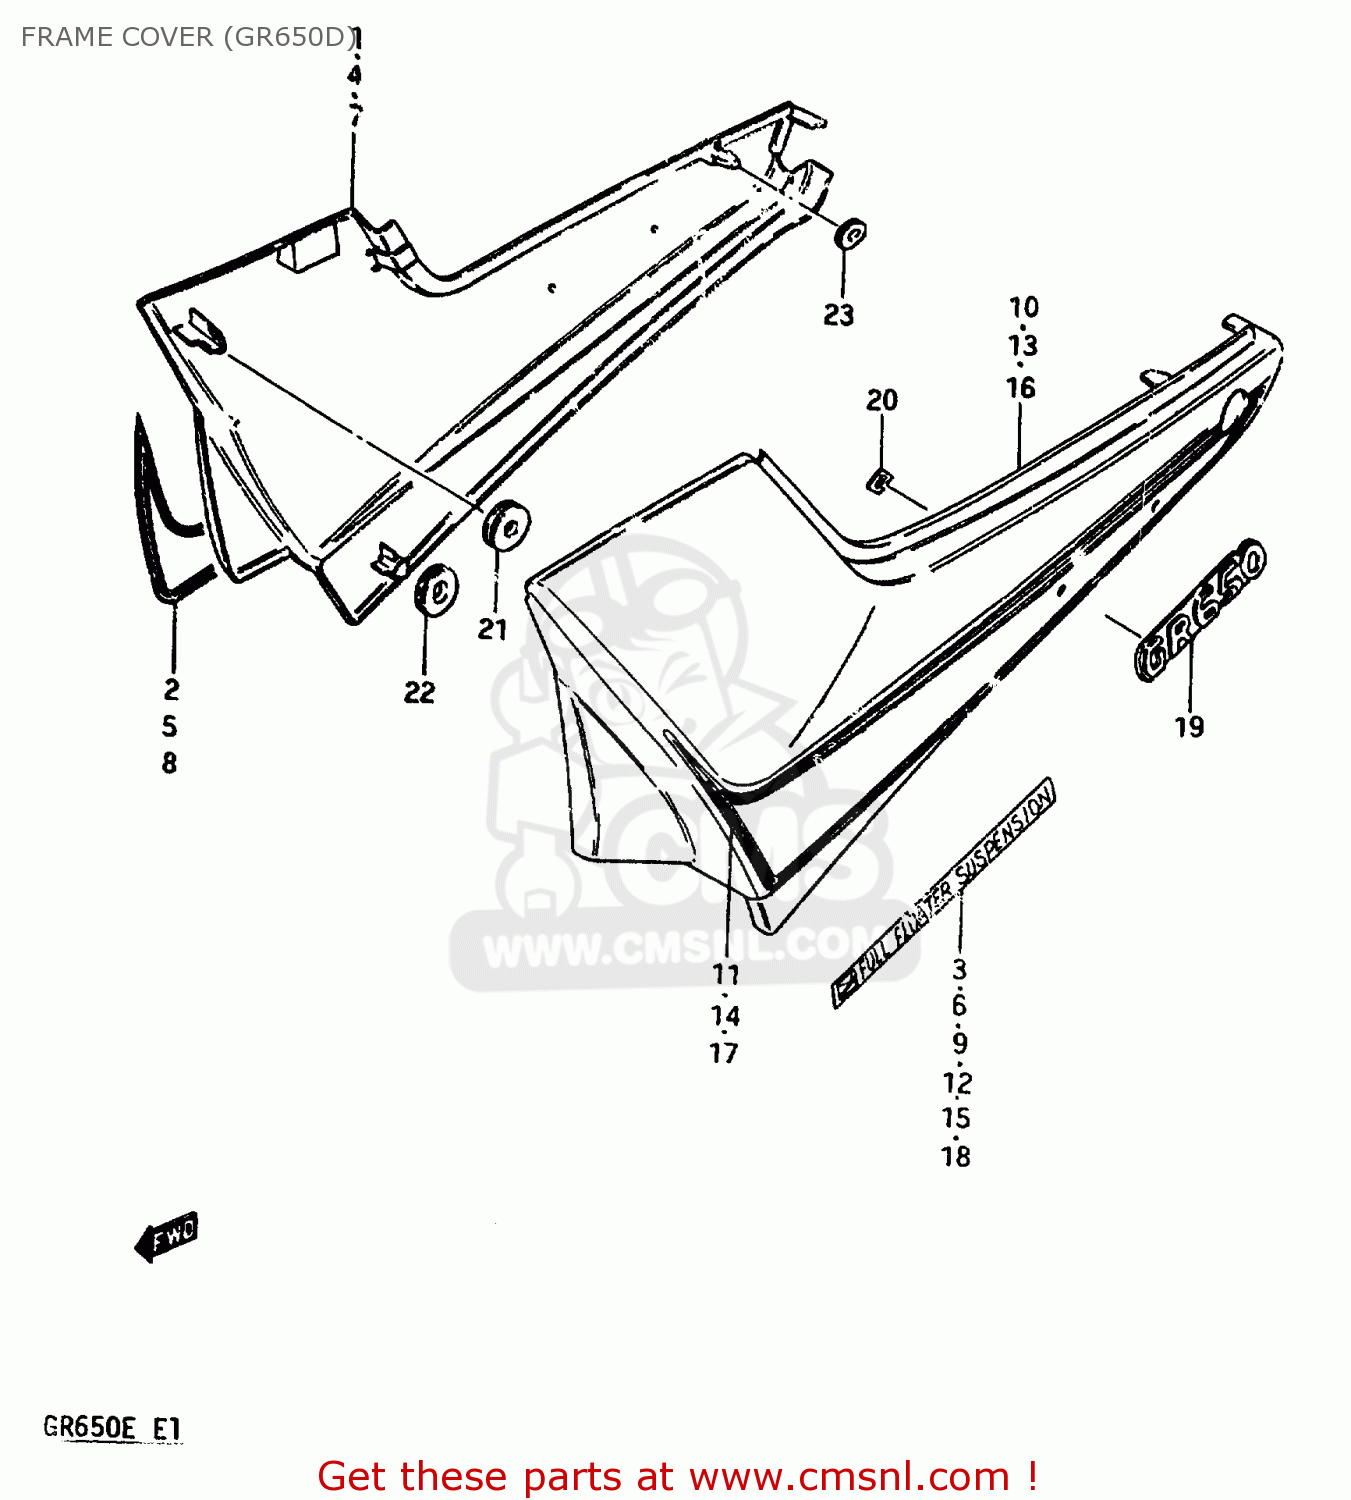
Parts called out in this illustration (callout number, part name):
1	COVER ASSEMBLY,FRAME,RIGHT
2	TAPE SET,FRAME COVER,RIGHT
3	EMBLEM
4	COVER, FRAME RH (SILVER)
5	TAPE, RH
6	EMBLEM
7	COVER, FRAME RH (BLACK)
8	TAPE SET, FRAME COVER RH
9	EMBLEM
10	COVER ASSEMBLY,FRAME,LEFT
11	TAPE, LH
12	EMBLEM
13	COVER, FRAME LH (SILVER)
14	TAPE, LH
15	EMBLEM
16	COVER, FRAME LH (BLACK)
17	TAPE SET, FRAME COVER LH
18	EMBLEM
19	EMBLEM,FRAME COVER
20	NUT
21	CUSHION
22	CUSHION
23	CUSHION
